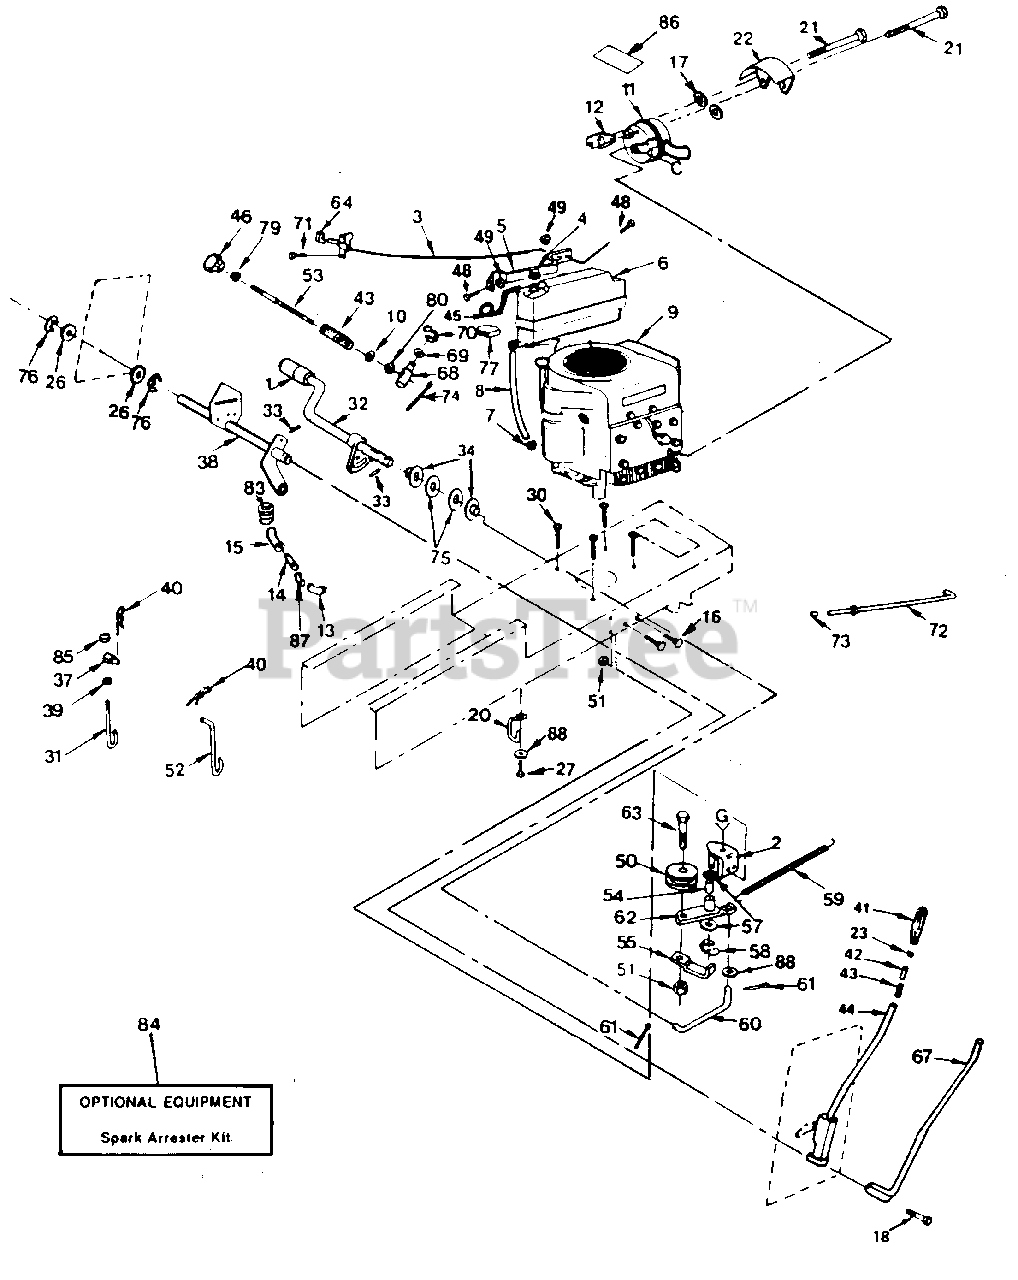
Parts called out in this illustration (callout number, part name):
1	Pedal Cover (AYP part number)
2	Clutch Bracket Assembly (AYP part number)
3	Throttle Control (AYP part number)
4	Fuel Cap (AYP part number)
5	Fuel Tank Support (AYP part number)
6	Fuel Tank (AYP part number)
7	Hose Clamp (AYP part number)
8	Fuel Line (AYP part number)
9	Engine, Briggs & Stratton, Model No. 281707, Type No. 1413-0
10	Washer 13/32 x 5/8 x 16 Ga. (AYP part number)
11	Muffler (AYP part number)
12	Exhaust Gasket (AYP part number)
13	Street Elbow (AYP part number)
14	STD Pipe Nipple (AYP part number)
15	Elbow (AYP part number)
16	Carriage Bolt 3/8-16 x 3/4 (AYP part number)
17	Washer (AYP part number)
18	Hex Bolt (AYP part number)
20	L.H. Chassis Belt Retainer (AYP part number)
21	Shoulder Bolt (AYP part number)
22	Heat Shield Muffler (AYP part number)
23	Plunger Button (AYP part number)
26	Washer (AYP part number)
27	Thd. Roll Washer Hex Screw (AYP part number)
30	Thd. Roll Washer Hex Screw (AYP part number)
31	Adjustable Lift Link (AYP part number)
32	Foot Pedal Shaft (AYP part number)
33	Roll Pin (AYP part number)
34	Nylon Bearing (AYP part number)
37	Lift Trunnion (AYP part number)
38	Lift Shaft Assembly (AYP part number)
39	Jam Hex Nut (AYP part number)
40	Spring Retainer (AYP part number)
41	Handle Grip (AYP part number)
42	Hand Lever Plunger (AYP part number)
44	Hand Kit Lever Assembly (AYP part number)
45	Tank Brace
46	Lift Adjust Handle (AYP part number)
48	Hex Bolt 5/16-18 x 3/4 Gr. 5 (AYP part number)
49	Locknut
50	Idler Pulley (AYP part number)
51	Nut
52	Lift Link (AYP part number)
53	Lift Adjust Rod (AYP part number)
54	Bearing (AYP part number)
55	Belt Retainer (AYP part number)
57	Hardened Washer (AYP part number)
58	Klip Ring (AYP part number)
59	Clutch Return Spring (AYP part number)
60	Clutch Link (AYP part number)
61	Cotter Pin (AYP part number)
62	Idler Arm (AYP part number)
63	Hex Bolt 3/8-16 x 1-1/2 (AYP part number)
64	Throttle Control Knob (AYP part number)
67	Lever Rod (AYP part number)
68	Depth Stop Trunnion
69	Washer 15/32 x 3/4 x 16 Ga. (AYP part number)
70	Klip Ring (AYP part number)
71	Thd. Cut. Washer Hd. Hex Screw (AYP part number)
72	Park Brake Rod (AYP part number)
73	Plunger Cap (AYP part number)
74	Cotter Pin (AYP part number)
75	Washer (AYP part number)
76	E-Ring (AYP part number)
77	Spacer Pad (AYP part number)
78	Ext. Tooth Lock Washer (AYP part number)
79	Jam Hex Nut (AYP part number)
80	Special Nut (AYP part number)
83	Oil Drain Plug (AYP part number)
84	Spark Arrester Kit (AYP part number)
85	Crownlock Jam Nut (AYP part number)
86	Maintenance Decal (AYP part number)
87	45?? Street Elbow (AYP part number)
88	Washer (AYP part number)
